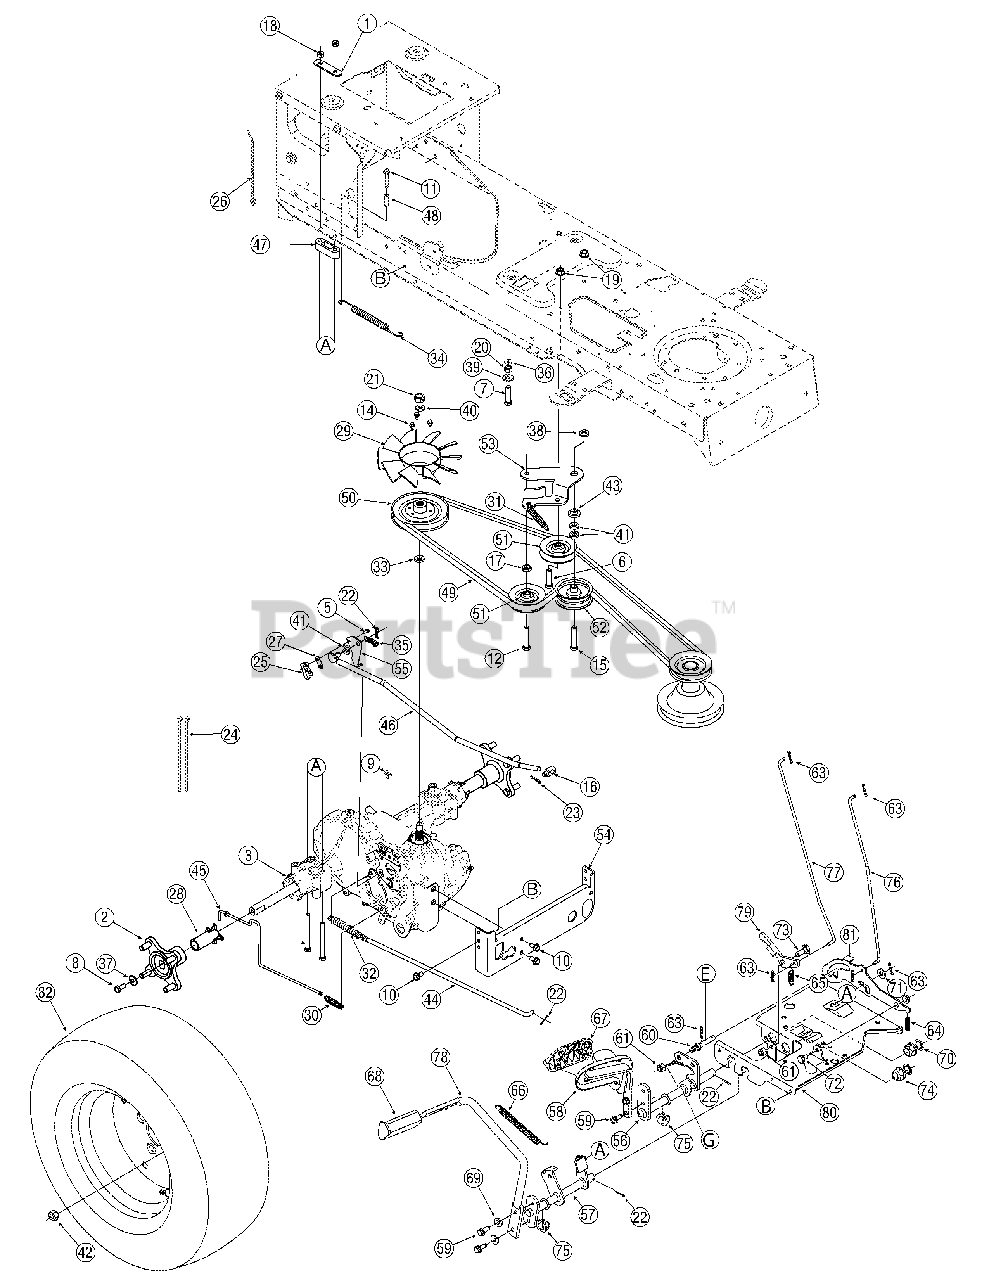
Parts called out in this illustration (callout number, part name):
2	Wheel Hub Assembly
3	Hydrostatic Transmission
4	Harness Assembly
5	AB Screw #8-18 x 0.375
6	TT Sems Screw 3/8-16 x 1.250
7	Hex Bolt 3/8-16 x 1.5
8	Screw, 5/16-24 x.750
9	TT Screw 1/4-20 x 0.5
10	AB Screw 5/16-12 x 0.75
11	Screw, 1/4-20 x 1.50
12	Screw, 3/8-16 x 1.50
13	Hex Bolt 5/16-18 x 3.5
14	Carriage Screw
15	Hex Bolt 3/8-16 x 2.25
16	Ferrule
17	Jam Nut 7/16-20
18	Flange Lock Nut, 5/16-18
19	Flanged Lock Nut 3/8-16
20	Flanged Lock Nut 3/8-16
21	Hex Nut, 1/2-20
22	Cotter Pin
23	Cotter Pin
25	Switch
27	Insulator Nut Plate
28	Sleeve, .765 x 2.410 Lg.
29	Blade Fan
30	Extension Spring
31	Extension Spring
32	Extension Spring
33	Wire Ring
34	Extension Spring
35	Extension Spring
36	Lock Washer
37	Bell Washer,.340 x.872 x.060
38	Flat Washer,.385 x 1.0 x .135
39	Flat Washer
40	Lock Washer
41	Flat Washer
42	Lug Nut 7/16-14
43	Shoulder Spacer
44	Brake Rod
45	Bypass Rod
46	Control Rod
47	Transaxle Spacer
48	Spacer,.260 x.372 x 1.030 Lg.
49	V Belt, A x 78" Lg
50	Input Pulley
51	Idler Pulley
52	Flat Idler Pulley
59	LD Screw 5/16-18 x 0.75
61	Flange Lock Nut, 3/8-16
62	Flange Lock Nut, 5/16-18
63	Pin, Cotter
64	Compression Spring
65	Extension Spring
66	Extension Spring
67	Control Pedal
68	Brake Control Pedal
69	Lock Washer 5/16
70	Flat Washer,.64 x 1.24 x.06
71	Flat Washer, .385 x .870 x .092
72	Shoulder Screw
73	Shoulder Screw
74	Hex Flange Bearing
75	Hex Flange Bearing
76	Brake Lock Control Rod
77	Cruise Control Rod
79	Cruise Latch
81	Hydro Lockout Bracket
82	Wheel Complete, 22 x 9.5 x 12
